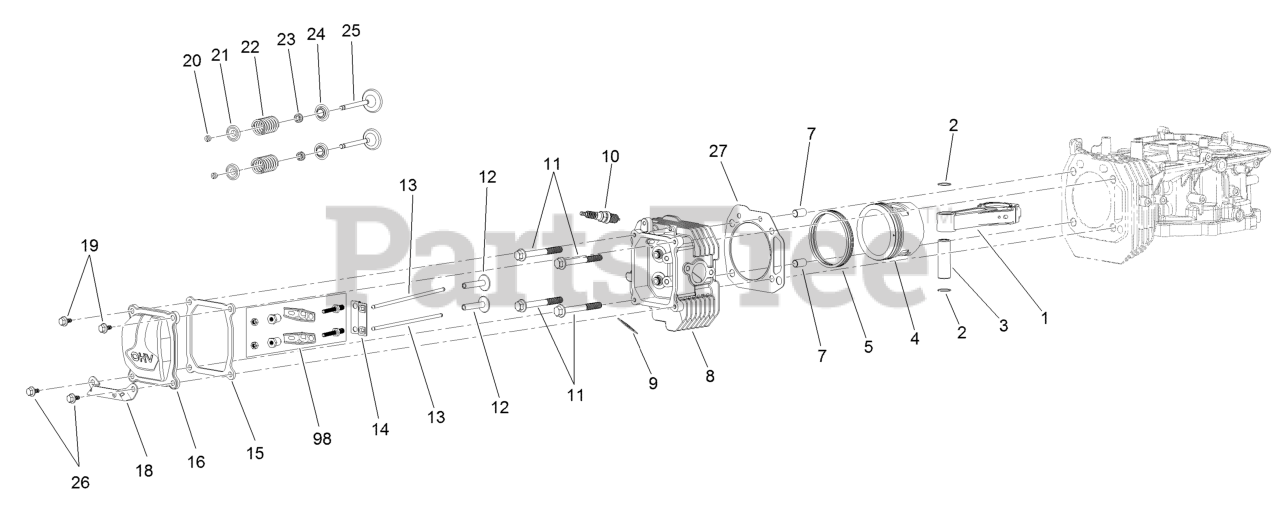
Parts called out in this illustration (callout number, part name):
1	CONNECTING ROD ASM
2	RING-RETAINING, PISTON PI
3	PIN-PISTON
5	RING SET
7	PIN-DOWEL
8	HEAD-CYLINDER
9	GASKET-EXHAUST
10	Plug-Spark
11	SCREW-HHF
12	LIFTER-VALVE
13	ROD-PUSH
14	PLATE-GUIDE, PUSH ROD
15	GASKET-COVER, VALVE
16	COVER-VALVE
18	BRACKET-MUFFLER
19	SCREW-SHOULDER, HHF
20	KEEPER-VALVE
21	RETAINER-SPRING, VALVE
22	SPRING-VALVE
23	SEAL-STEM, VALVE
24	SEAT-SPRING, VALVE
25	VALVE SET
26	SCREW-SHOULDER, HHF
27	GASKET-CYCLINDER
